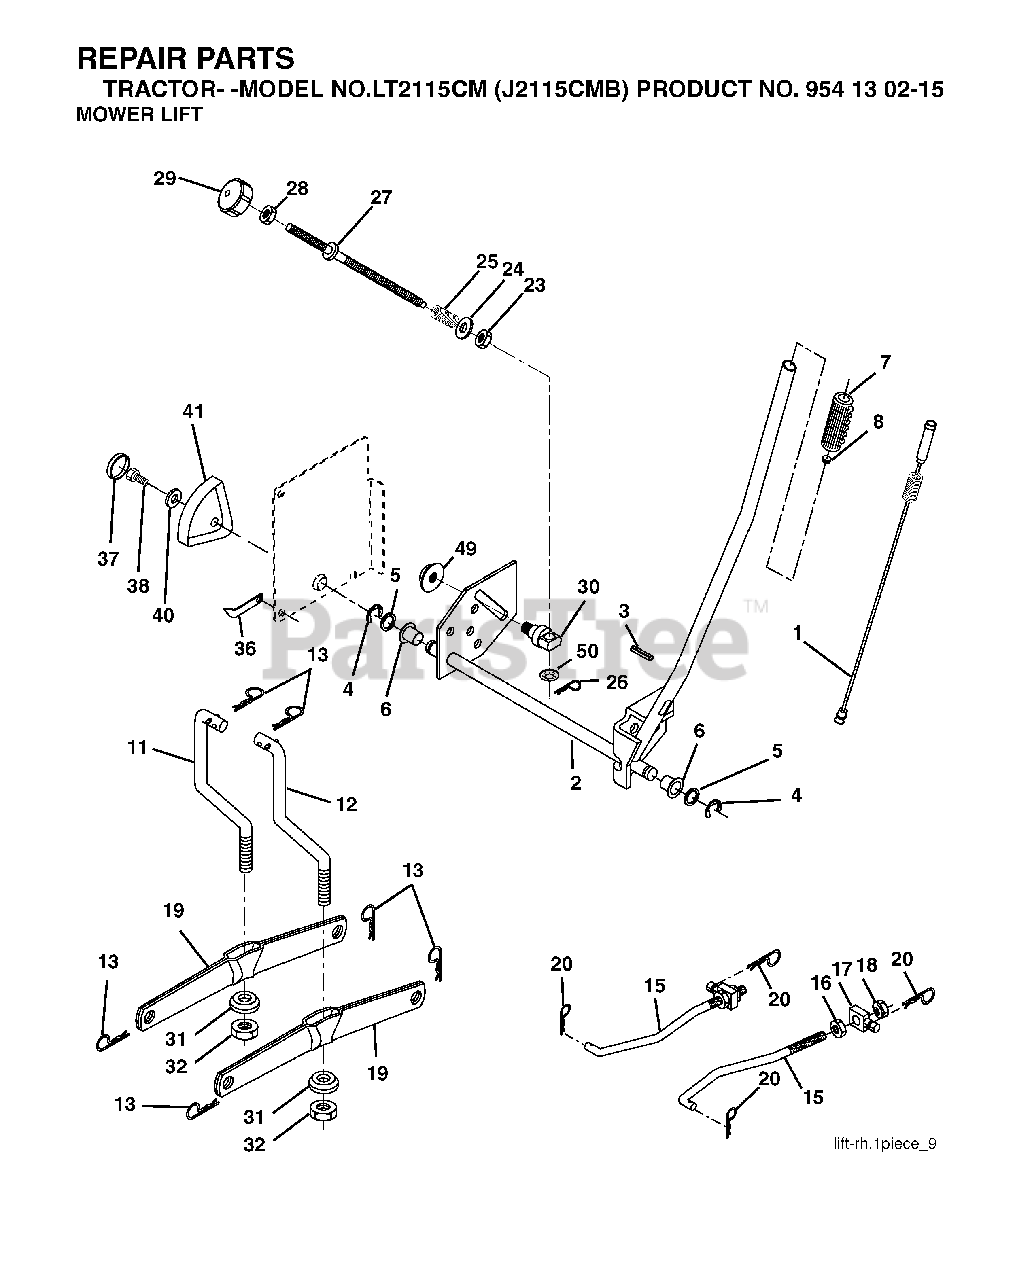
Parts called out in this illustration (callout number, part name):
1	WIRE ASM INNER W/ PLUNGER LT
2	SHAFT ASM R HANDLE
3	PIN GROOVE
4	RETAINING RING LT
6	BEARING.NYLON
7	GRIP HANDLE
8	PLUNGER BUT KIT
11	LINK
12	LINK
13	RETAINER-SPRNG RB
15	LINK.SUSPENSION.FRONT
16	NUT
18	NUT
19	ARM.REAR.SUSPENSION
20	SPRING RETAINER
25	SPRING**
26	RETAINER CLIP
27	ROD ADJ LIFT
28	NUT
29	KNOB INF 3/8-16
31	BEARING.PIVOT.LIFT
32	NUT CROWNLOCK 3/8-24
36	POINTER, HEIGHT INDICATOR
37	PLUG,HOLE
38	SCREW 5/16-18X1
41	HEIGHT INDICATOR
49	NUT
50	NUT PUSH M
